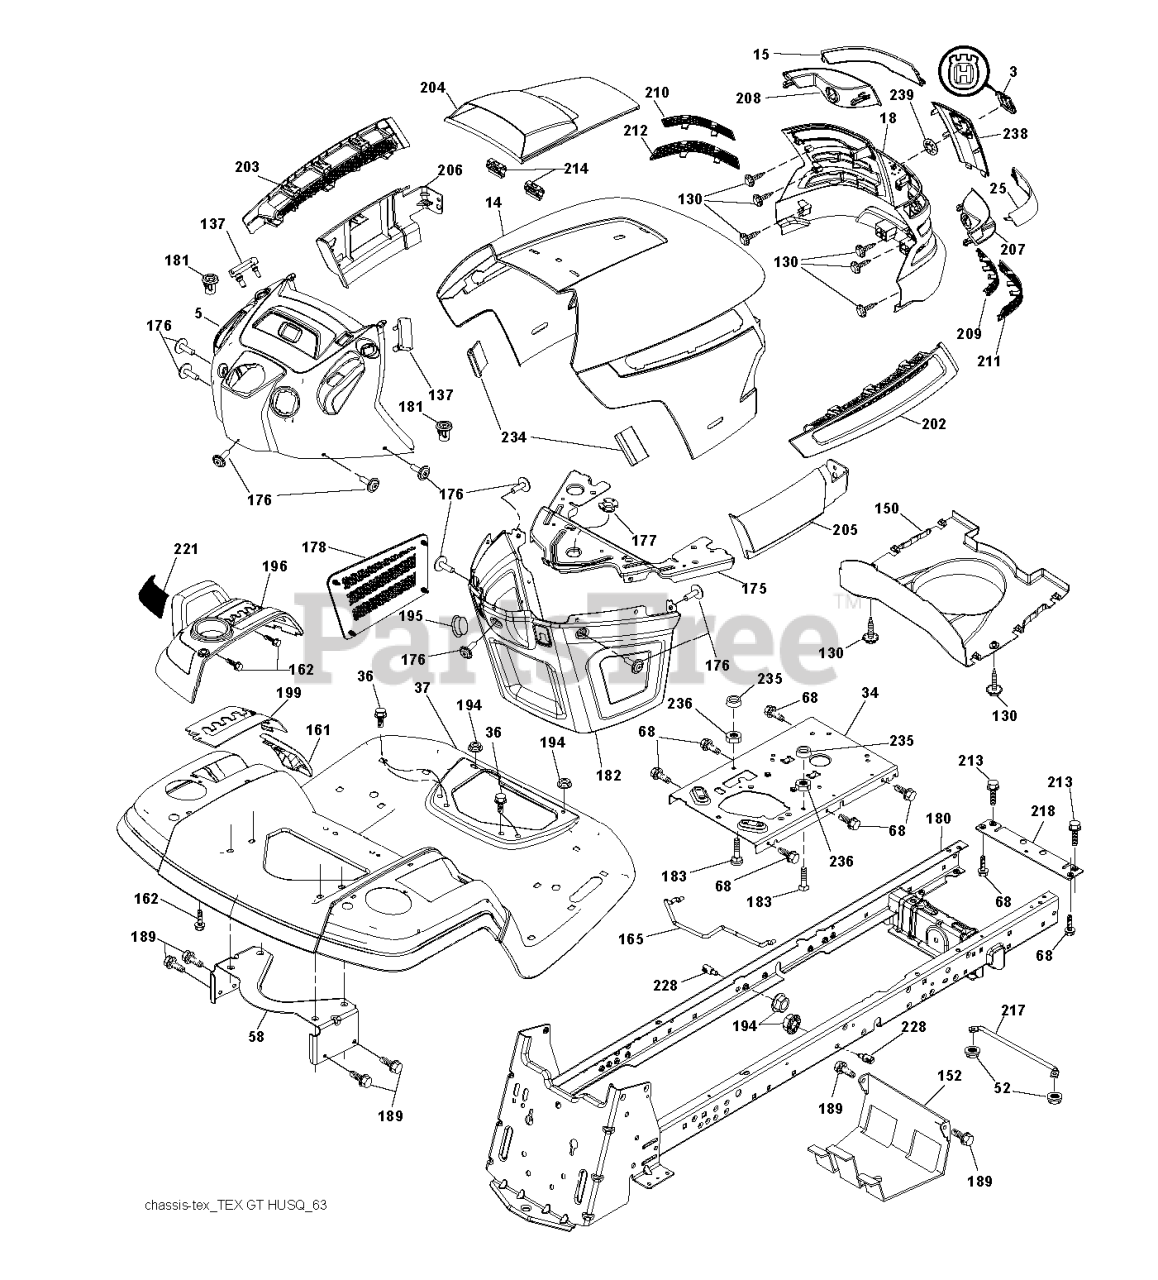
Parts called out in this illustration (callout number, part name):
3	RP LOGO
14	HOOD
15	LENS.LH.TEX.GT.HUSQ.CL
18	GRILL.ASM.HUSQ.TG/CRD.W/TRIM
25	LENS.RH.TEX.GT.HUSQ.CL
34	PLATE.ENGINE.WELDED.CHASSIS
36	SCREW 5/16"
37	FENDER.PNT.TX.GT.CH/FW.ORANGE
52	LOCKNUT
58	BRKT.SUPPORT.FNDR/TANK
68	Screw 5/16-18 x 1/2 Hex, Self Tapping 5/16-18 x 1/2
130	SCREW.#10 X 0.750.BOS
137	BUMPER DASH
150	AIR.DUCT.HOOD.TEX.GT.HUSQ
152	SHIELD.BROWNING.W/TEX
161	CONSOLE.FUEL.WINDOW.HU
162	SCREW.HI-LO.CONSOLE
165	SUPPORT.TANK.REAR.W/TEX
175	PLATE.CROSSMEMBER.HUSQ
176	SCREW.#10-24X5/8.RN.QU
177	BUSHING, STEERING
178	CARGO.ASM.NET.TXGT.W/C
180	CHASSIS.GT.SLOPED.DRAWBAR.
181	BUSHING.MNT.FEND.CRGO.
182	DASH.LOWER.COMMON.12V.ADAPTOR
183	BOLT.5/16-18X1-1/4 FULL THD
189	SCREW
194	NUT LOCK HEX FLANGE 5/16-18
195	PLUG.HOLE.DASH.LOWER.12V.BLK
196	RP CONSOLE.ASM.DECKLFT.W/
199	PLATE.DECK.LIFT.HUSQVARNA.GT
202	VENT.SIDE.HOOD.HUSQ.RH.GREY
203	VENT.SIDE.HOOD.HUSQ.LH.GRAY
204	HOOD VENT
205	SKIRT.HOOD.SIDE.HUSQ.RH.GREY
206	SKIRT.HOOD.SIDE.HUSQ.LH.GREY
207	BEZEL.RH.TEX.GT.HUSQ
208	BEZEL.LH.TEX.GT.HUSQ
209	INSERT.HEX.GRILL.HUSQ.GREY
210	INSERT.HEX.GRILL.HUSQ.
211	INSERT.HEX.GRILL.HUSQ.
212	INSERT.HEX.GRILL.HUSQ.
213	BOLT
214	CLIP.RETAINER.TINNER.
217	ROD.PIVOT.HOOD
218	X-PIECE.HOOD.STOP.NON/
221	REFLECTOR.LH.TEX GT HU
228	STUD.FASTNER.W/ANTI-ROTATE
234	BUMPER.HOOD.TEX.HUSQVARNA
235	SPACER FENDER
236	NUT.CENTERLOCK.5/16-
238	TRIM.HUSQ.TG/CRD.SERVICE
239	NUT PUSH M
